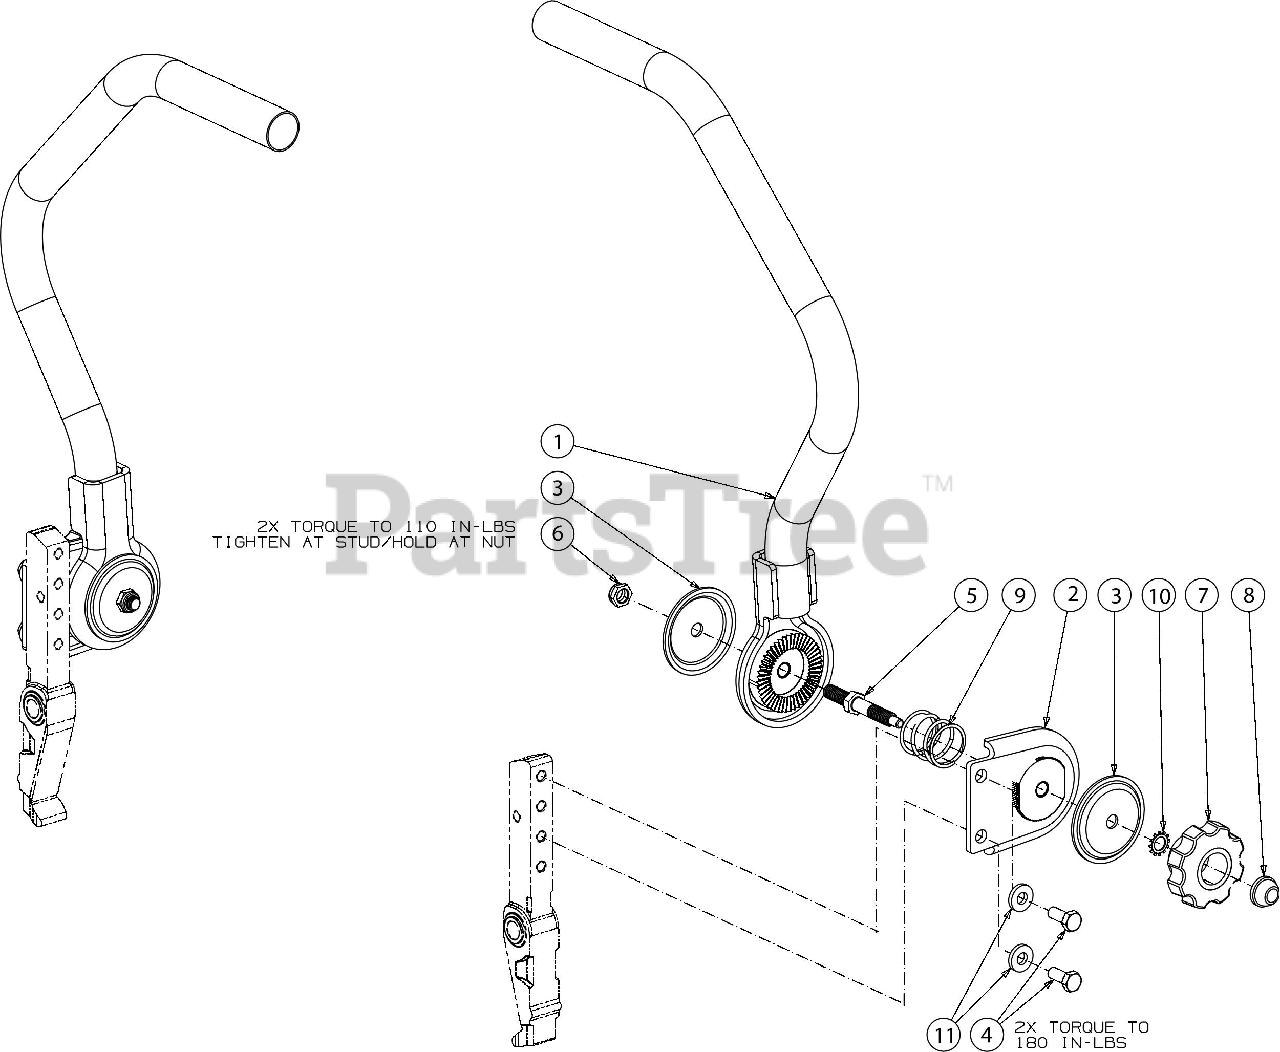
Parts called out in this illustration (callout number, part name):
2	LAPBAR ADJUSTMENT PLATE ASSEMBLY
4	SCREW 5/16-18 x .750
5	LAPBAR ADJUSTMENT STUD
6	TOP LOCK NUT
7	LAPBAR ADJUSTMENT KNOB
8	PUSH CAP .250
9	COMPRESSION SPRING
10	LOCK WASHER 3/8
11	FLAT WASHER
